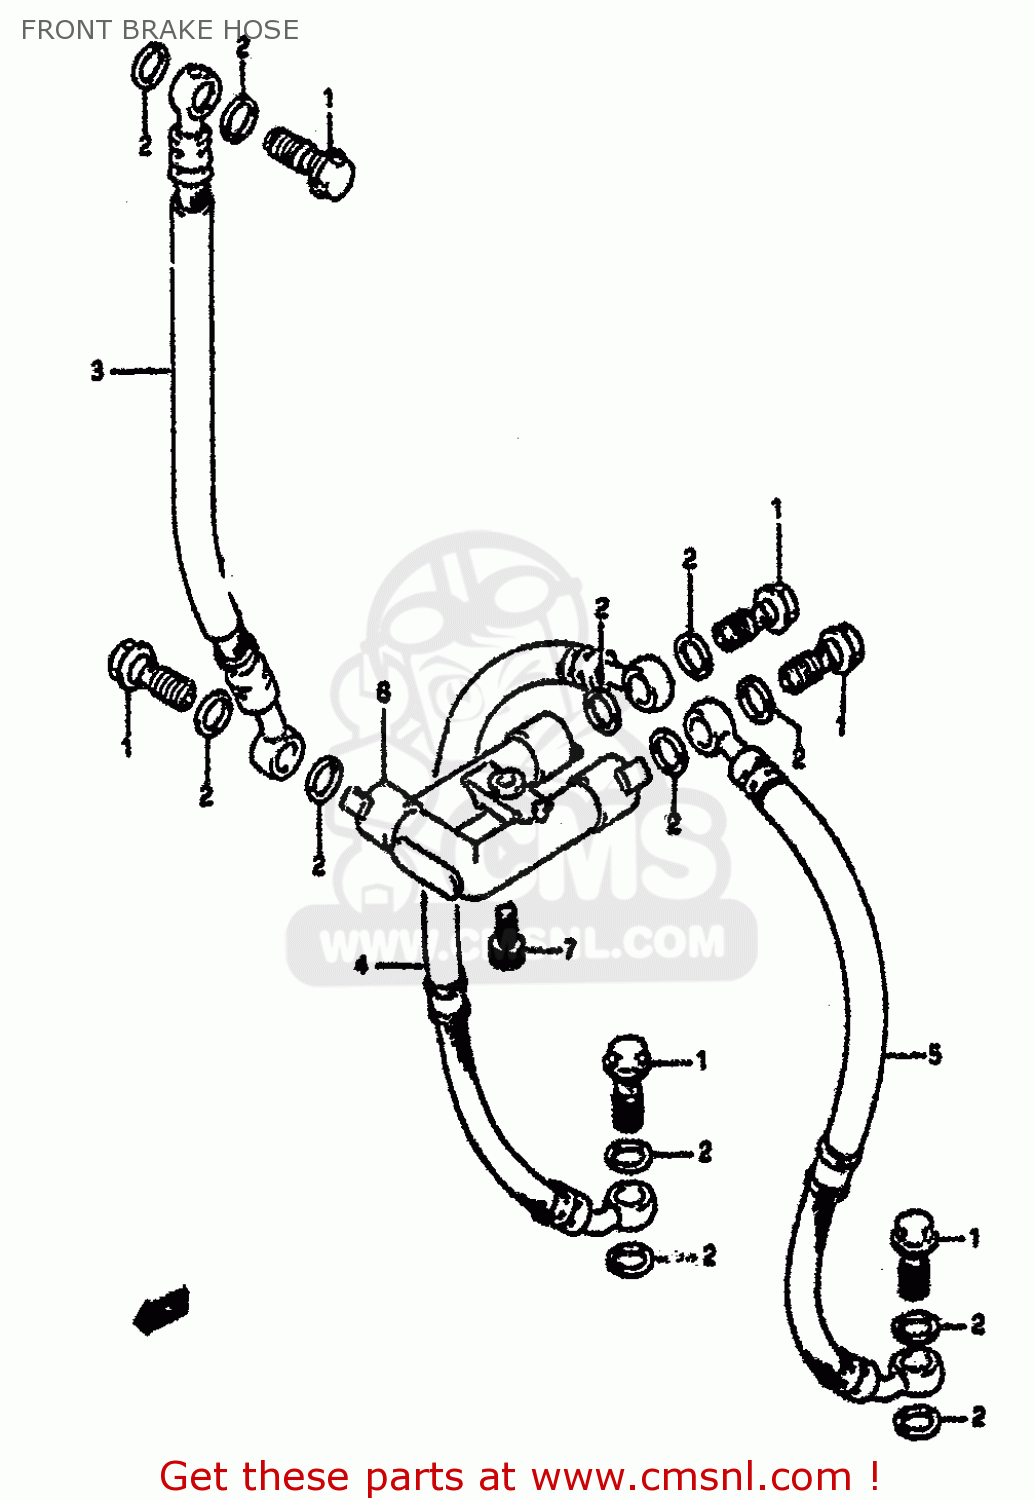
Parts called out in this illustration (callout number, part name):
1	BOLT UNION
2	WASHER(10X15X1.5)
3	HOSE,FRONT BRAKE
4	HOSE,FRONT BRAKE NO.2
5	HOSE,FRONT BRAKE NO.2
6	JOINT,BRAKE HOSE
7	BOLT
